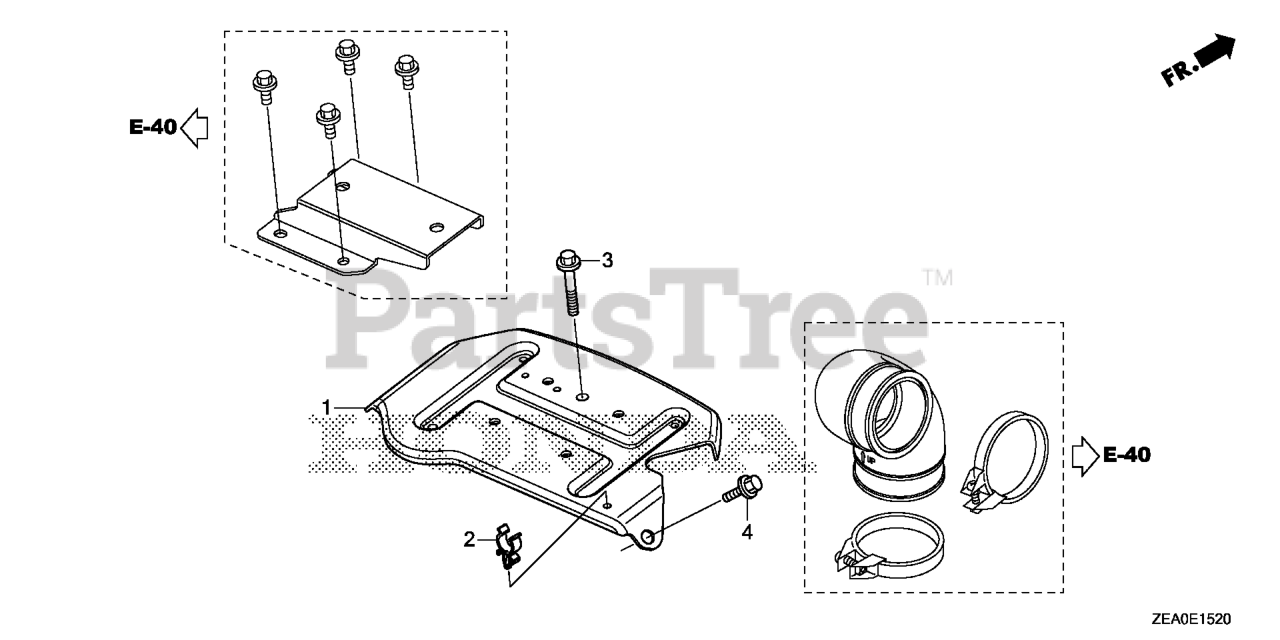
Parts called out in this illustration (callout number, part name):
1	STAY, AIR CLEANER (NOT AVAILABLE)
2	CLAMP, HOSE (NOT AVAILABLE)
3	BOLT, FLANGE (6X32)
4	BOLT, FLANGE (8X16) Use from Engine SN 1000016.
